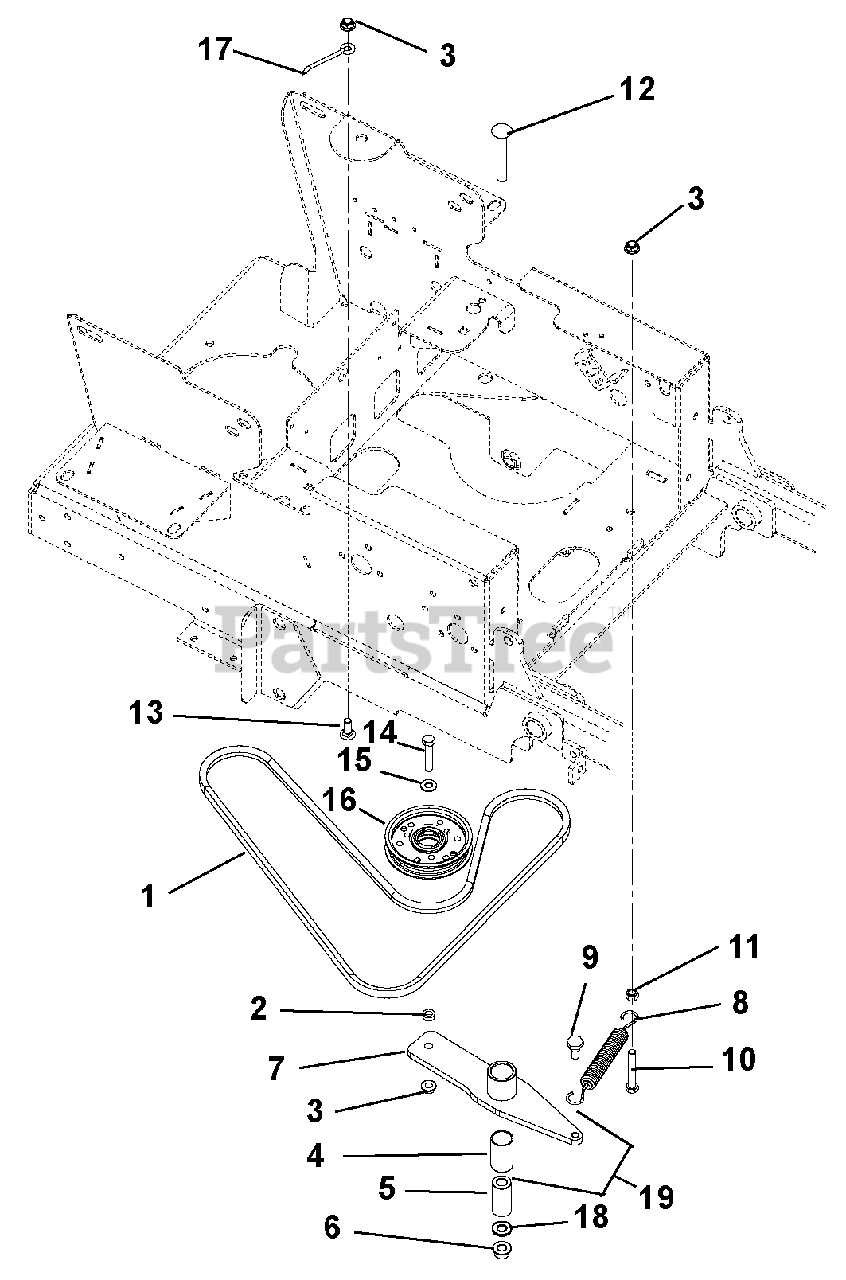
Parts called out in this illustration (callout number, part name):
1	Belt, 4L 67.47 Wrapped
2	Washer, Flat Steel. .406 x 1.375 x .135
3	Nut, .38-16 Nyloc Flange
4	Bushing, 1.00 x 1.125 x 1.936
5	Bushing, Spacer .502 x .997 x 2.03
6	Nut .50-13 Nyloc Flange
7	Weldment, Hydro Drive Idler Arm
8	Spring, Extension
9	Bolt, Shoulder EP .38-16 x .30 Hex
10	Bolt, Hex .38-16 x 2.50 Grade 5
11	Nut, Locking Center .375-16
12	Bolt, Hex .50-13 x 3.25 Grade 5
13	Bolt, Round Head Square Neck .38-16 x 1.00 Grade 5
14	Bolt, Hex .38-16 x 2.00 Grade 5
15	Washer, Flat Steel .406 x .812 x .065
16	Assembly, 4" Idler (.75 Wide)
17	Belt Finger
18	Washer, Flat Steel .511 x 1.441 x .125
19	Assembly, Idler Pivot Arm (Includes item 4 and 7)
